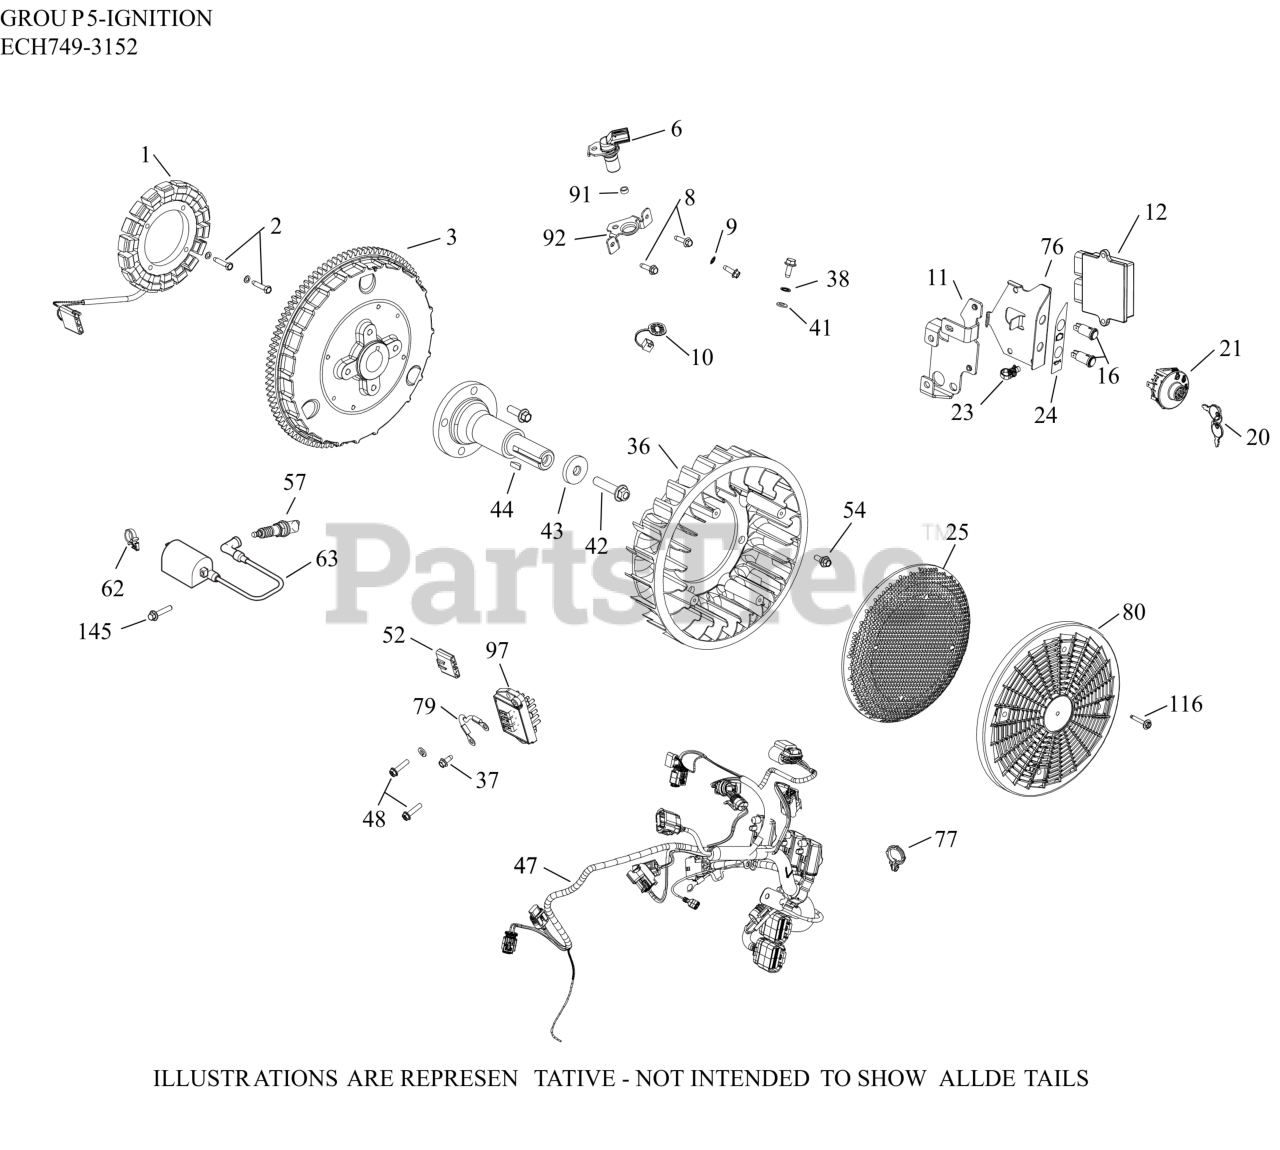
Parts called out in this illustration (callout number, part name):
1	KIT, 15 / 20 AMP STATOR
2	SCREW, THREAD FORMING
3	FLYWHEEL, ASSEMBLY
6	SENSOR, SPEED
8	SCREW, THREAD FORMING
9	WASHER, INT TOOTH LOCK #10
10	CAP, CONNECTOR
11	BRACKET, ECU
12	MODULE, ECU ECH749
16	LIGHT, INDICATOR
20	KEY, SET OF 2
21	KIT, KEY SWITCH (SNAP-IN)
23	TIE, WIRE
24	DECAL, WARNING LIGHT
25	KIT GRASS SCREEN
36	FAN-USE 24 755 253-S
37	SCREW, THREAD FORMING
38	WASHER, INT TOOTH LOCK 1/4"
41	WASHER, FLAT 1/4" (O.D. 1/2")
42	SCREW, HEX FLANGE
43	WASHER, FLAT
44	KEY, 3/16" X 5/8"
47	HARNESS, WIRING ASSEMBLY
48	SCREW, HEX FLANGE HI-LO
52	CONNECTOR
54	BOLT, SHOULDER
57	SPARK PLUG, RFI
63	COIL, IGNITION - EFI (RFI/EMC)
76	BRACKET, WARNING LIGHT
77	RETAINER, WIRE HARNESS
80	SCREEN, GRASS
92	BRACKET, SENSOR
97	REGULATOR, RECTIFIER (20-30AMP,FW W/OVP)
116	SCREW, FLG SEMS M4x.7x25
145	SCREW, HEX FLANGE
